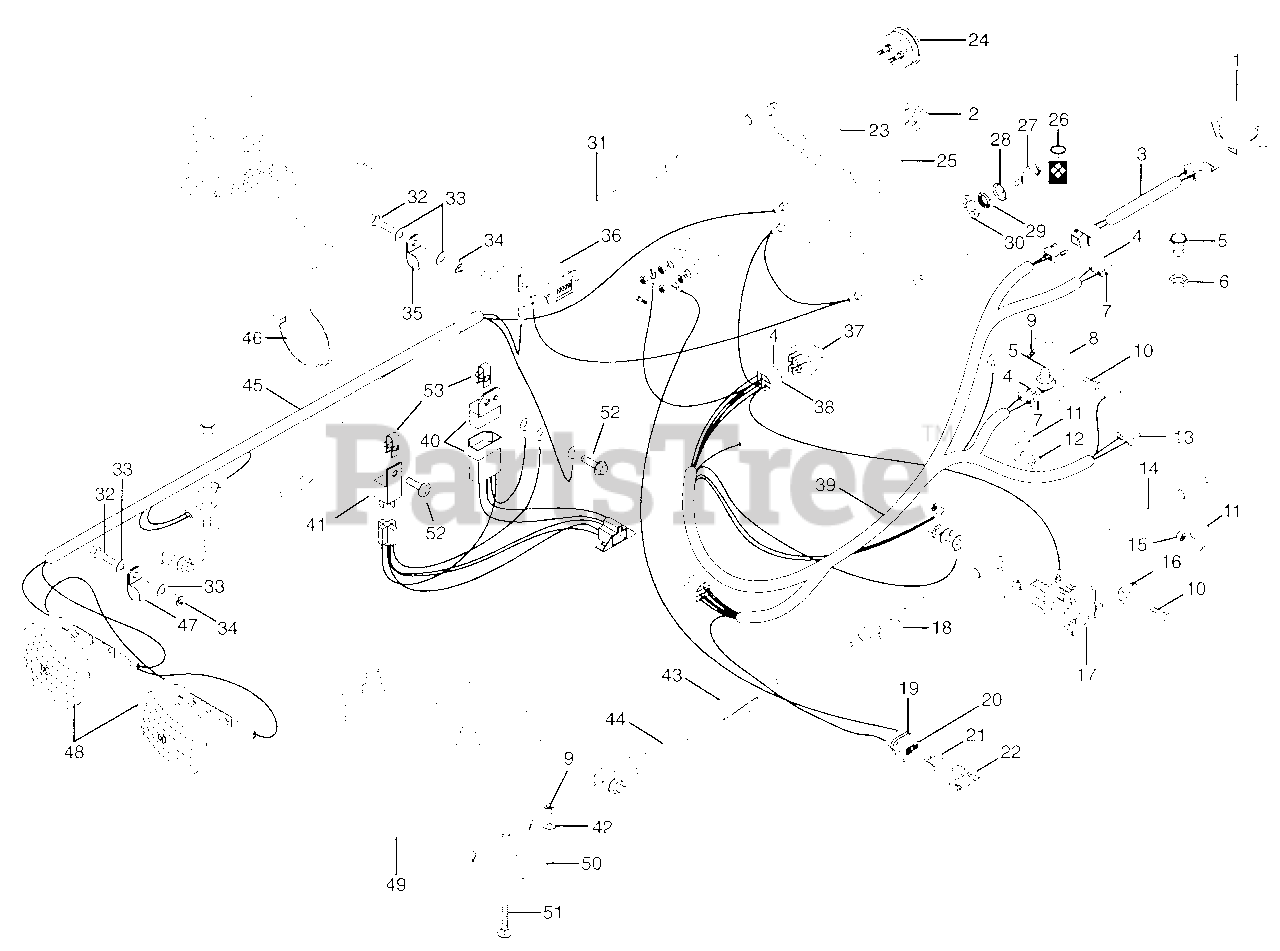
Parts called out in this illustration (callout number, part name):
1	Switch-Seat
2	Switch Assembly
3	Harness-Wiring Seat Switch
4	Terminal
5	Switch-Neutral Start N.O.
6	Nut-Stamped .56-18
7	Connector 2 Wire Switch
8	Bracket-Switch
9	Nut-Locking-Center .250-20
10	Bolt-Hex .25-20 x .75 Grade 5
11	Clamp
12	375-16 Grade 2
13	Connector
14	Cable Starter
15	Nut-Locking-Center .375-16
16	Nut-Speed .25-20
17	Solenoid
18	Boot-Insulator
19	Assembly-Connector Weather Tight
20	Terminal For 14-16 Gauge Wire
21	Fuse-25 AMP
22	Cover
23	Light-Indicator
24	Gauge-Ammeter
25	Switch-Light
26	Key Chain
27	Ignition Switch Key
28	Cap-Ignition Switch
29	Nut-Panel .562-24
29	Nut-Panel .625-32
30	Washer-Lock Internal .563 x .040
30	Washer-Lock Internal .625 x .045
31	Cable-Negative Battery
32	Bolt-Hex .31-18 x 1.00 Grade 5
33	Washer-Flat-Steel .344 x .688 x .065
34	Nut-Locking-Nylon .312-18 Grade 2
35	Clamp-Steel 1.0
36	Hour Meter
37	Ignition Switch
37	Switch-Key
38	Connector
39	Harness-Wiring
40	Kit-Interlock Module-Delay
41	Relay
42	Washer-Flat-Steel .281 x .62 x .065
43	Cover-Battery Terminal
44	Cable-Battery to Magneto Switch
45	Harness-Wiring Ground & Lights
46	Tie-Cable
47	Cable Clamp
48	Head Light
49	Battery-12Volt
50	Clamp
51	Bolt-Round Head Square Neck .25-20 x 1.75
52	Screw-Machine-Hex Washer Head 10-24 x .75
53	Nut-Retainer 10-24
